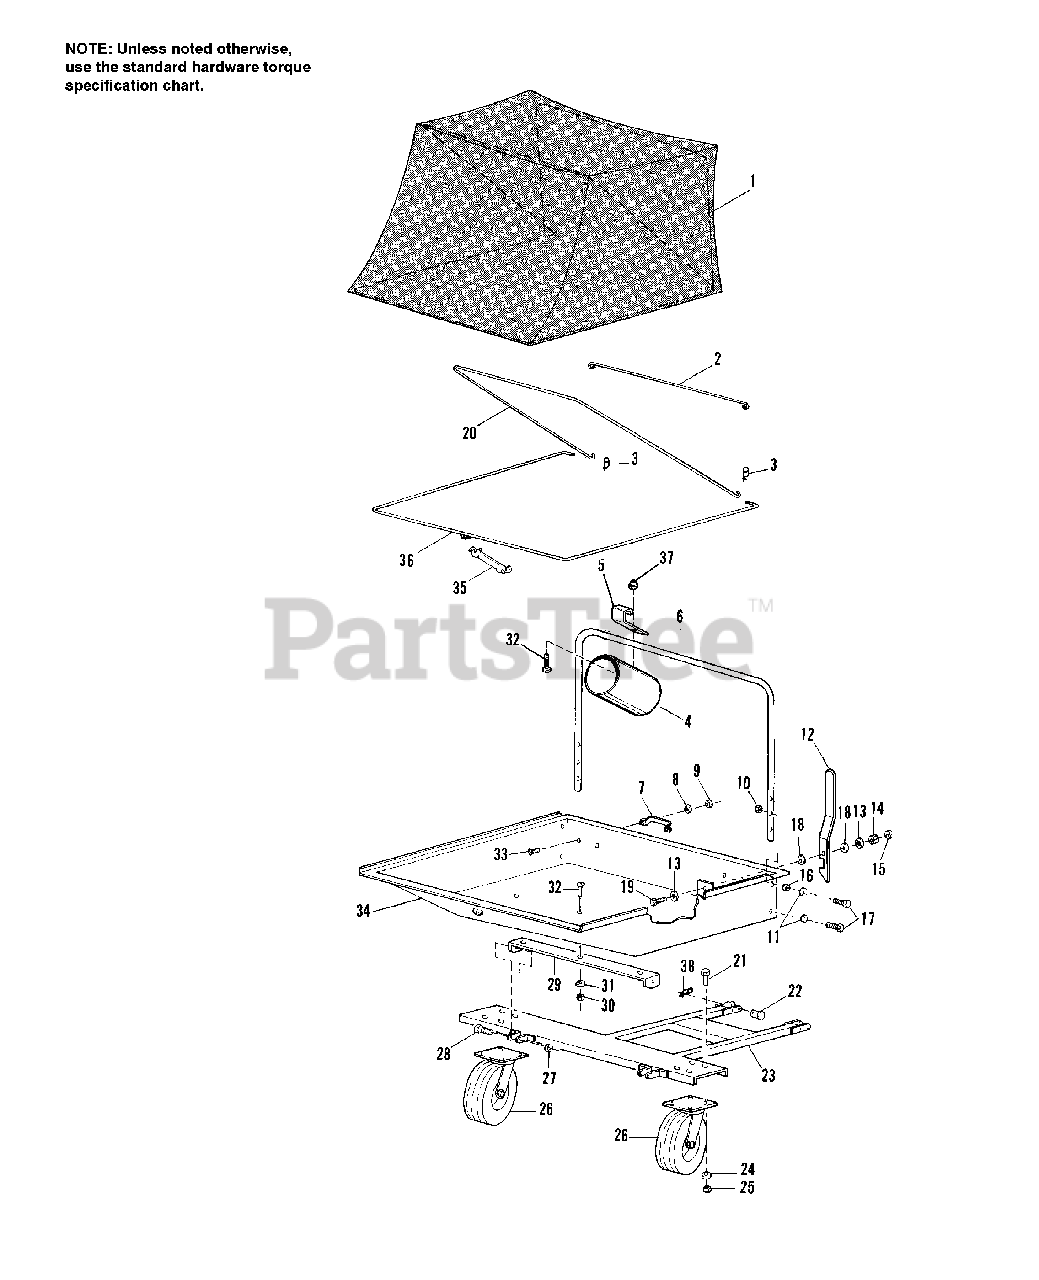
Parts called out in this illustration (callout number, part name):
2	ROD, Straight
3	CLIP
4	SLEEVE, Plastic, Connecting
5	CLAMP, Sleeve
6	TUBE, Support
7	HANDLE, Lift
8	LOCKWASHER, 1/4
9	NUT, Hex, 1/4-20
10	NUT, Lock, 5/16-18
11	WASHER, Flat, 5/16
12	HANDLE, Latch
13	WASHER, Spring, 5/16
14	NUT, Hex, Full, 5/16-18
15	NUT, Jam, 5/16-18
16	SPACER, Plastic, 5/16
17	CAPSCREW, Hex Hd., 5/16-18 x 1-1/2
18	WASHER, 11/32 x 3/4
19	CAPSCREW, Hex Hd., 5/16-18 x 1-1/4
20	ROD, Support
21	BOLT, Hex, 3/8-16 x 1
22	PIN, 1/2 x 1-1/4
24	WASHER, Flat, 3/8 S.A.E.
25	NUT, Hex Lock, 3/87-16
26	WHEEL, Swivel, 410/350-4
27	NUT, Hex Lock, 1/2-13
28	CAPSCREW, Hex Hd., 1/2-13 x 1-1/4
29	"U" BRACKET
30	NUT, Hex, 5/16-18
31	LOCKWASHER, 5/16
32	BOLT, Slotted, Truss Hd.
33	CAPSCREW, Hex Hd., 1/4-20 x 1/2
35	STRAP, Rubber, 6"
36	ROD, Support
37	NUT, Nylon insert, 1/4-20
38	SAFETY CLIP
